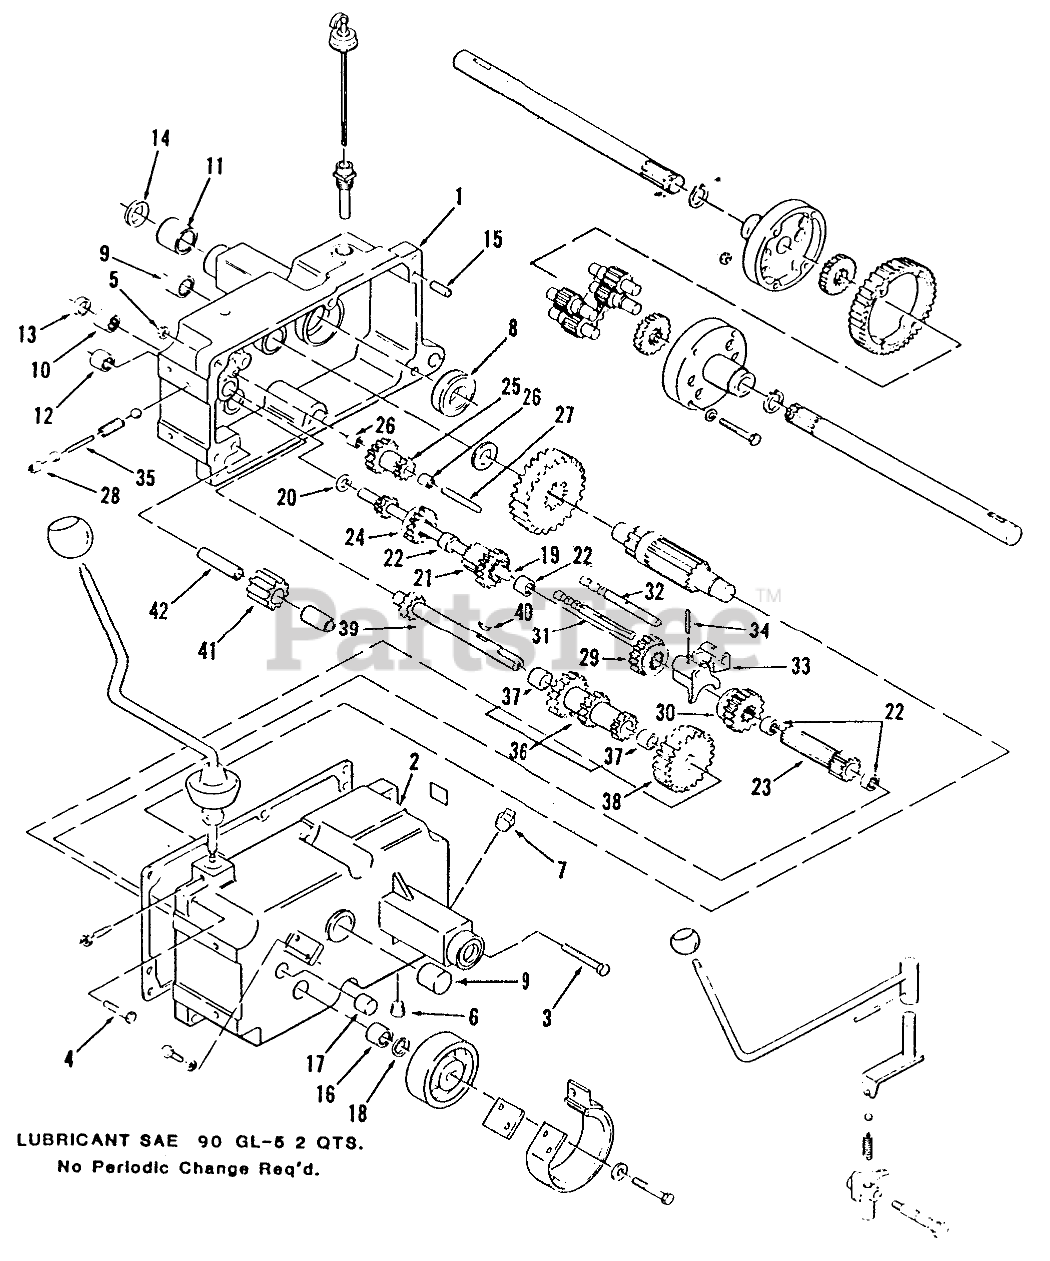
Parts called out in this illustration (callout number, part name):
1	CASE TRANS RH
2	CASE TRANS LH
3	HHCS
4	Bolt
5	Nut
6	PLUG 1/4 PIPE ALLEN
7	Plug
8	BEARING-BALL
9	BEARING-NEEDLE
10	BEARING-NEEDLE
11	BEARING-NEEDLE
12	BEARING-NEEDLE
13	SEAL-OIL
14	OIL SEAL
15	PIN-DOWEL
16	BEARING-NEEDLE
17	Bearing Needle
18	SEAL-OIL
19	SHAFT-INPUT
20	WASHER-THR
21	GEAR
22	BEARING-NEEDLE
23	GEAR
24	GEAR-SLIDING
25	Gear
26	BEARING-NEEDLE
27	GEAR-SHAFT REDUCTION
28	CUP-PLUG
29	GEAR-HI AND 2ND
30	GEAR-LOW AND REVERSE
31	RAIL-SHIFT
32	RAIL-REAR SHIFT
33	FORK-SHIFT
34	PIN-ROLL
35	PIN-SHIFT
36	GEAR-CLUSTER
37	BUSHING-BRONZE
38	GEAR-CLUSTER SHAFT
39	Cluster Shaft
40	KEY-WOODRUFF
41	GEAR/BUSHING ASM-REVERSE IDLER
42	PIN-DIFFERENTIAL
43	BUSHING
44	ASSY-DIPSTICK
45	NIPPLE-TRANS FILL
46	GASKET-TRANSMISSION
47	SETSCREW
48	Nut
49	COVER-DUST
50	WASHER-THRUST
51	GEAR ASM
52	PINION SHAFT
55	BALL-DETENT
56	SPRING-SHIFT STOP
57	BOLT-DETENT
58	SHIFT ASM
59	Shift Fork
60	BALL-DETENT
61	SPRING-SHIFT STOP
62	SHIFT ROD ASM
63	PIN-SPIROL
64	END CAP-DIFFERENTIAL
65	Bolt 3/8-16 x 3 1/4
66	WASHER
68	DIFFERENTIAL BULL GR
70	GEAR-PINION, 11T
71	AXLE GEAR
72	AXLE-REAR
73	Snap Ring
74	ASM-Rod
75	Knob
76	MANUAL
